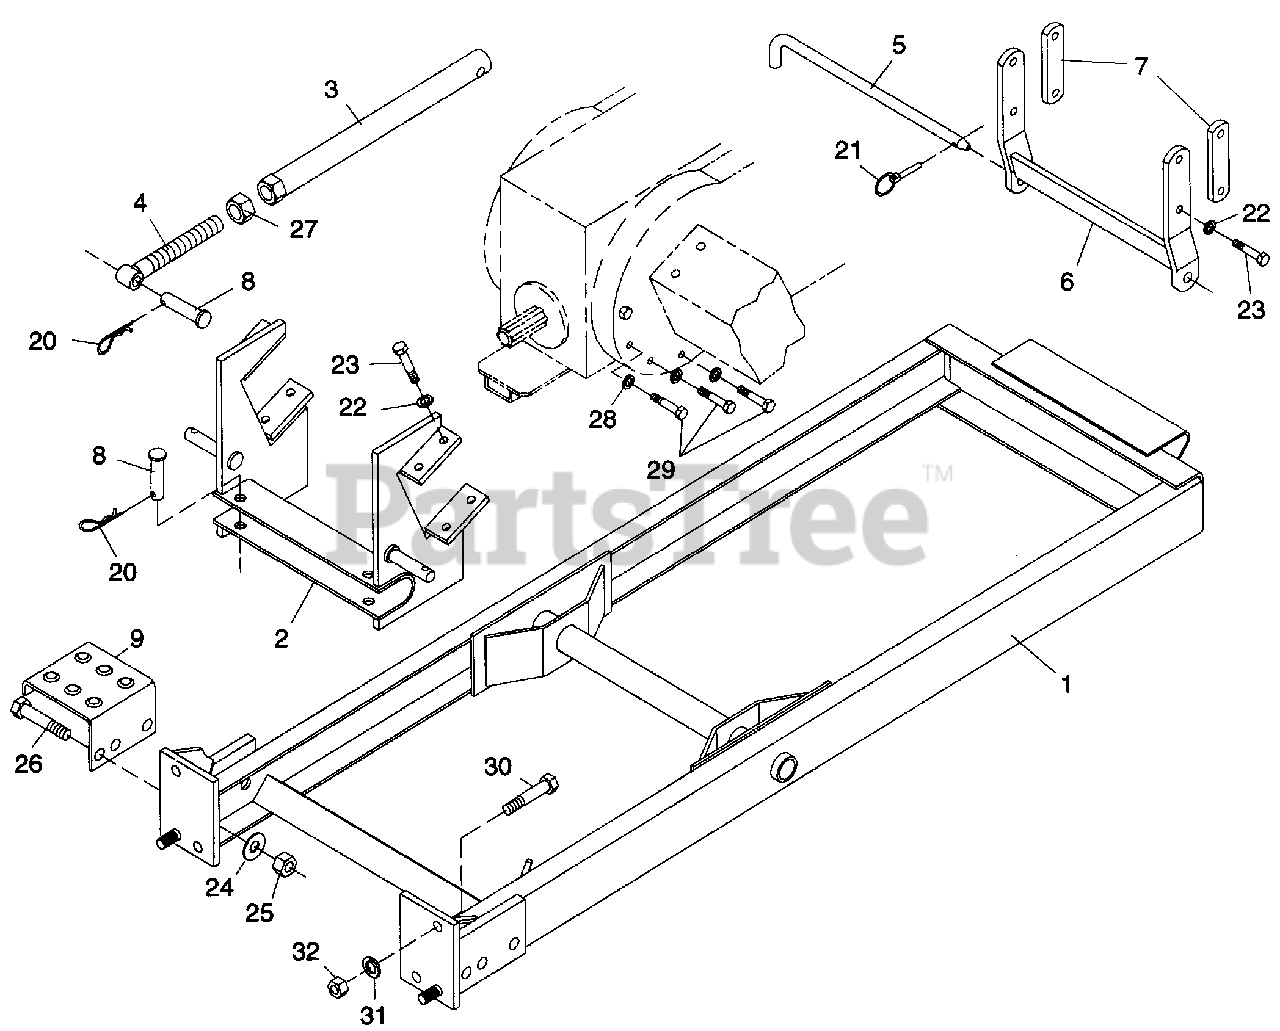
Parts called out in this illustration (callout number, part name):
1	Backhoe sub-frame 24.4 x 74 assembly
2	Rear mounting bracket assembly
3	Outer link assembly, 19.5
4	Inner top link assembly
5	3/4 x 17.75 Lock pin
6	Front mounting bracket assembly
7	Link, .50 x 1.50 x 6.25
8	3/4 x 3-1/4 Clevis pin
20	1/8 Safety pin
21	1/4 x 1-3/4 Klik pin
22	9/16 Standard lockwasher
23	14mm x 2.0P x 35mm Hex head cap screw
24	7/8 Lockwasher
25	7/8 Hex nut
26	7/8 NC x 2-1/2 Hex head cap screw GR5
27	1" NC Hex nut
28	1/2 Lockwasher
29	12mm x 1.75P x 80mm Hex head cap screw
30	3/4 NC x 2 Hex head cap screw GR5
31	3/4 Lockwasher
32	3/4 Nut
